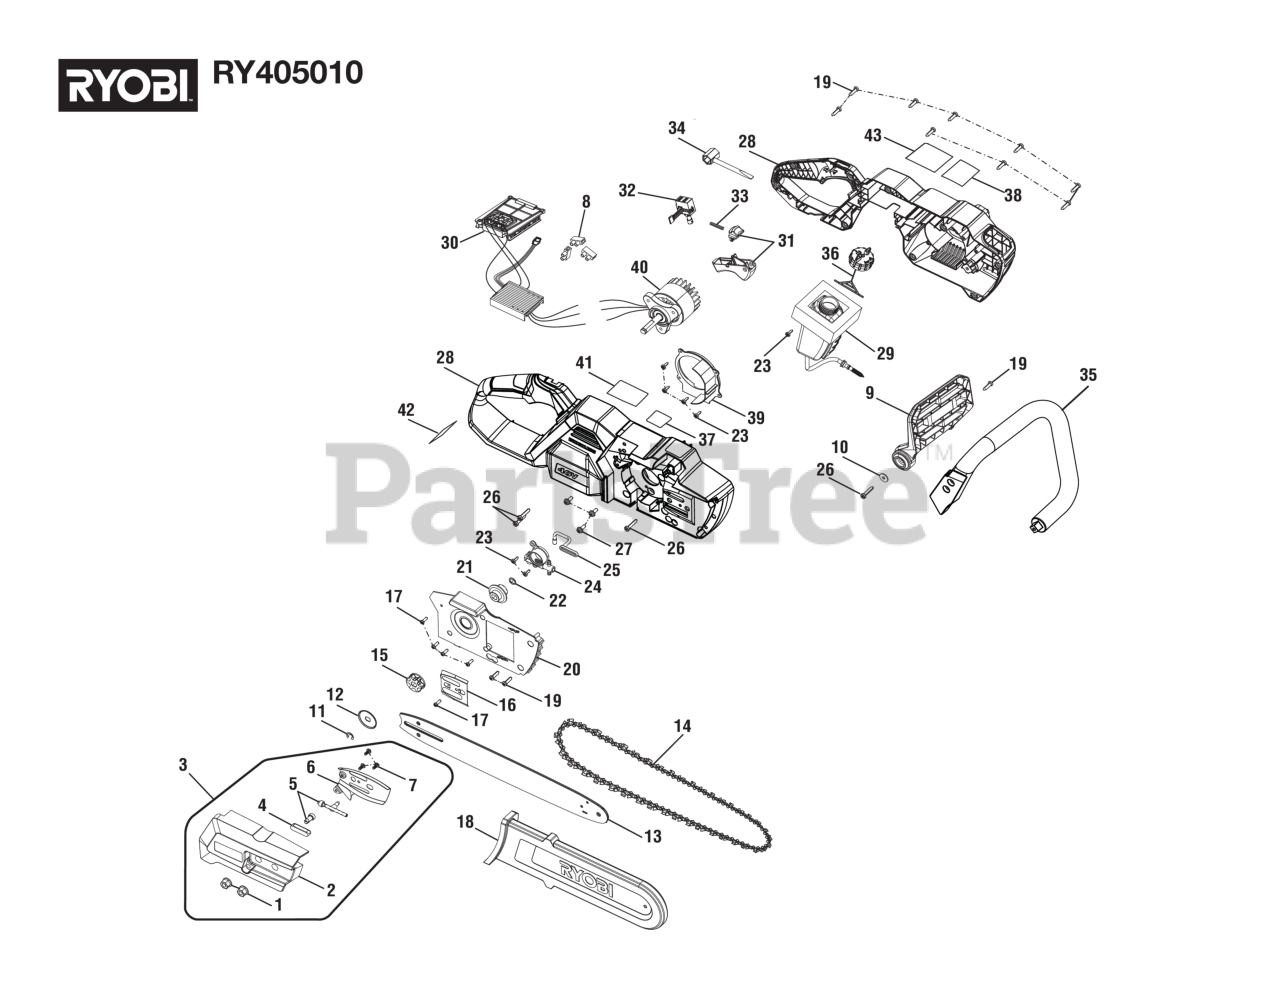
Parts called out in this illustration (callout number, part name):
1	Hex Nut (5/16-18 Flange)
2	Bar Cover
3	Bar Cover Assembly (Inc. Key Nos. 1-2 & 4-7)
4	Rubber Plate
5	Driving Adjustment Gear Assembly
6	Guide Plate
7	Screw (M4 x 10 mm, T20 Torx Pan Hd.)
8	Terminal Block w/Screw
10	Washer (ID5.2 x OD16 x 1.5t)
12	Washer (Special)
13	Bar (14 in.)
14	Chain (14 in.)
16	Guide Plate Bar
17	Screw, M4-18 x 12mm, T20 Torx Pan Head
19	Screw (T20 x 15 mm)
20	Cover Housing
21	Oil Pump Drive
23	Screw (M4.2 x 12 mm, T20 Torx Pan Hd.)
25	Oil Output Tube
26	Screw (T20 x 20 mm)
27	Screw, T25, M5X8, Steel, Black ZincePlat
28	Housing Assembly (Inc. Key Nos. 37-38 & 41-43)
29	Oil Tank Assembly
30	Motor Controller and Battery Connector Assembly
31	Switch Trigger and Lock-Out Button Assembly
33	Compression Spring (Trigger Lock)
35	Front Handle
36	Oil Tank Cap Assembly
37	Height Adjust Label
38	Warning Icon Label (Left)
39	Volute Cover
40	Motor
41	Data Label
43	Warning Label (English/Spanish, Left)
